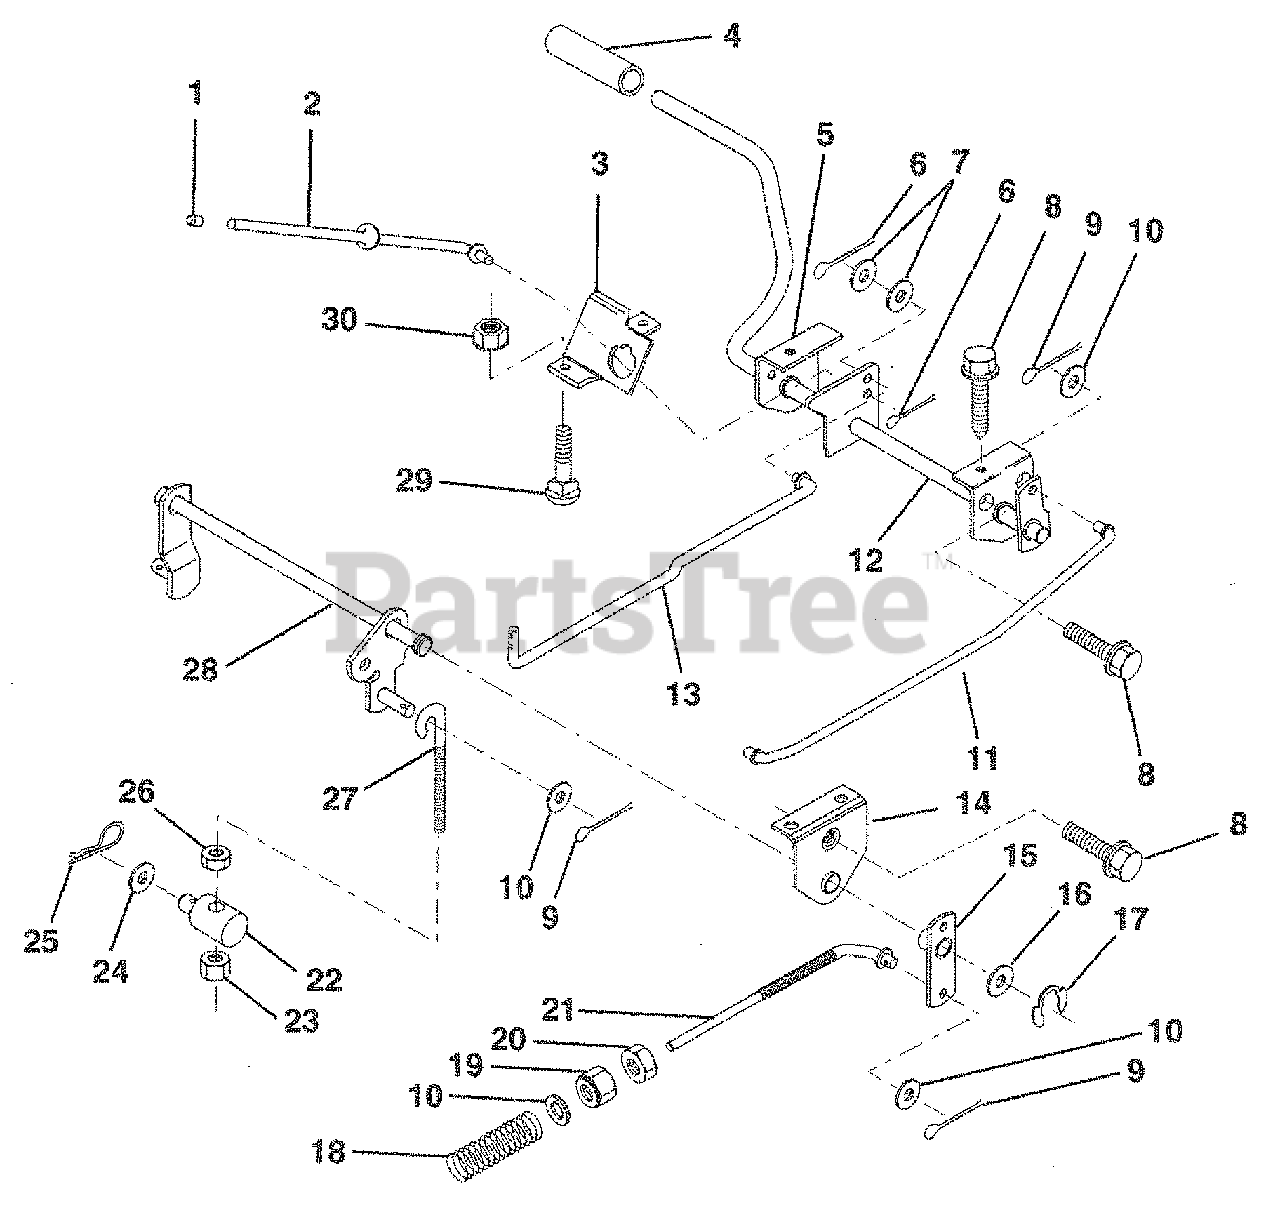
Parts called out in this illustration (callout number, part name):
1	Cap, Plunger
2	Rod, Parking Brake
3	Bracket, Parking Brake
4	Cover, Pedal
5	Bracket, Clutch/Brake Pedal, L.H.
6	Pin, Cotter 3/32 x 3/4
7	Washer 13/32 x 5/8 x16 Ga.
8	Screw, Hex, Thd. Roll. 5/16 -18x1/2
9	Pin, Cotter 1/8 x 3/4
10	Washer 13/32 x 13/16 x 16 Ga.
11	Rod, Brake Front
12	Assembly, Clutch/Brake Pedal
13	Rod, Clutch
14	Bracket, Lift, Shaft
15	Assembly, Brake, Pivot, Arm
16	Washer 25/32 x 1-1/8 x 16 Ga.
17	Ring, Klip
18	Spring, Brake Rod
19	Locknut, Hex w/Washer Insert 3/8-16 UNC
20	Nut, Hex, Jam 3/8-16 UNC
21	Rod, Rear Brake
22	Trunnion, Lift
23	Nut, Crownlock 3/8 -16 UNC
24	Washer 13/32 x 1 1-1/4 x12 Ga
25	Spring, Retainer
26	Nut, Centerlock 3/8-16 UNC
27	Link, Threaded
28	Assembly, Rear Mower Lift
29	Bolt Carriage 5/16 -18 UNC x 3/4
30	Nut, Keps 5/16 -16 UNC
